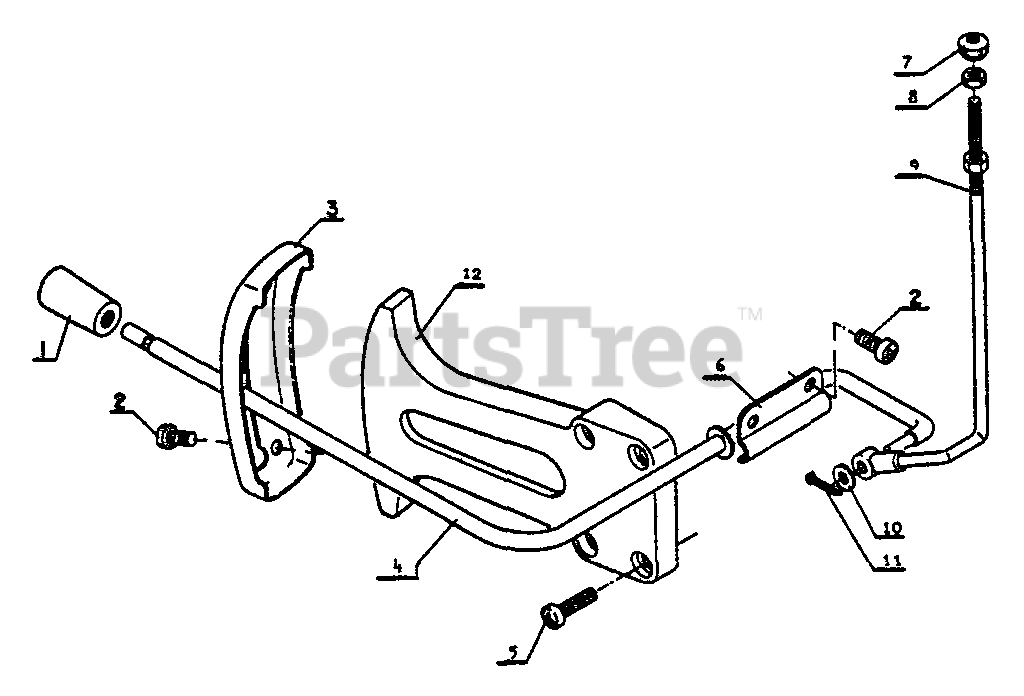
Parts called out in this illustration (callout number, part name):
1	KNOB, THROTTLE CONTROL
2	SCREW - 5X10
3	DIAL
4	LEVER, THROTTLE
5	SCREW - 5X18
6	RETAINER
9	ROD, THROTTLE
10	WASHER - 4
12	BRACKET, DIAL
